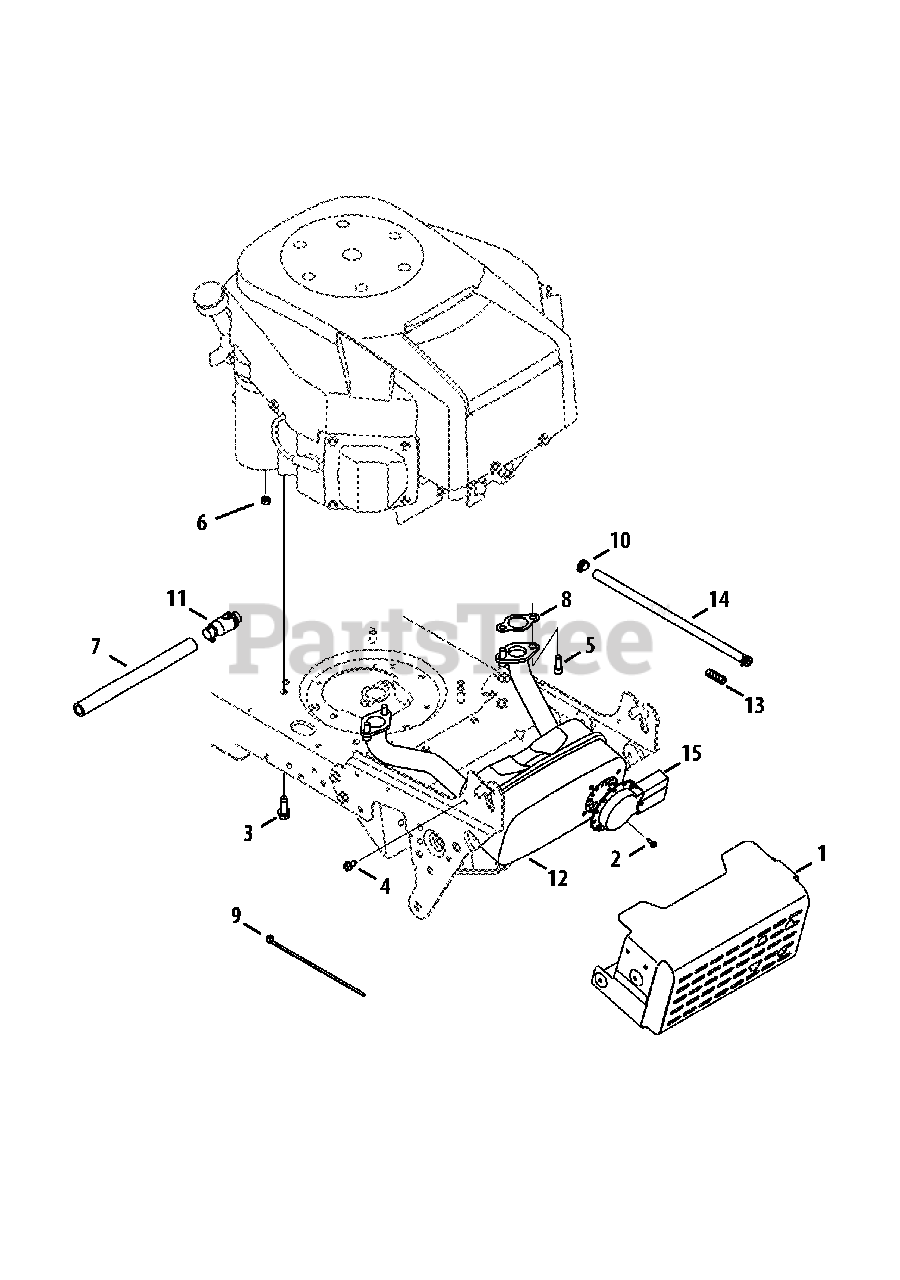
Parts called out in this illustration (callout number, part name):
1	Shield Ass’y, Muffler
2	Screw, Ab, #8-18, 0.500,
3	Screw, Self-tapping, 3/8-16, 1.000,
4	Screw, Self-tapping, 1/4-20, 0.500,
5	Screw, Socket Head, 5/16-18, .750
6	Nut, Sems, 1/4-20
7	Hose, Extension, Oil Drain
8	Gasket, Exhaust, Briggs
9	Cable, Tie, 3/16 x .05 x 7.4
10	Clamp, Hose, .490 Dia.
12	Muffler, Briggs Twin
14	Hose, Fuel, Low Permeation, 1/4
15	Deflector, Muffler, Long
